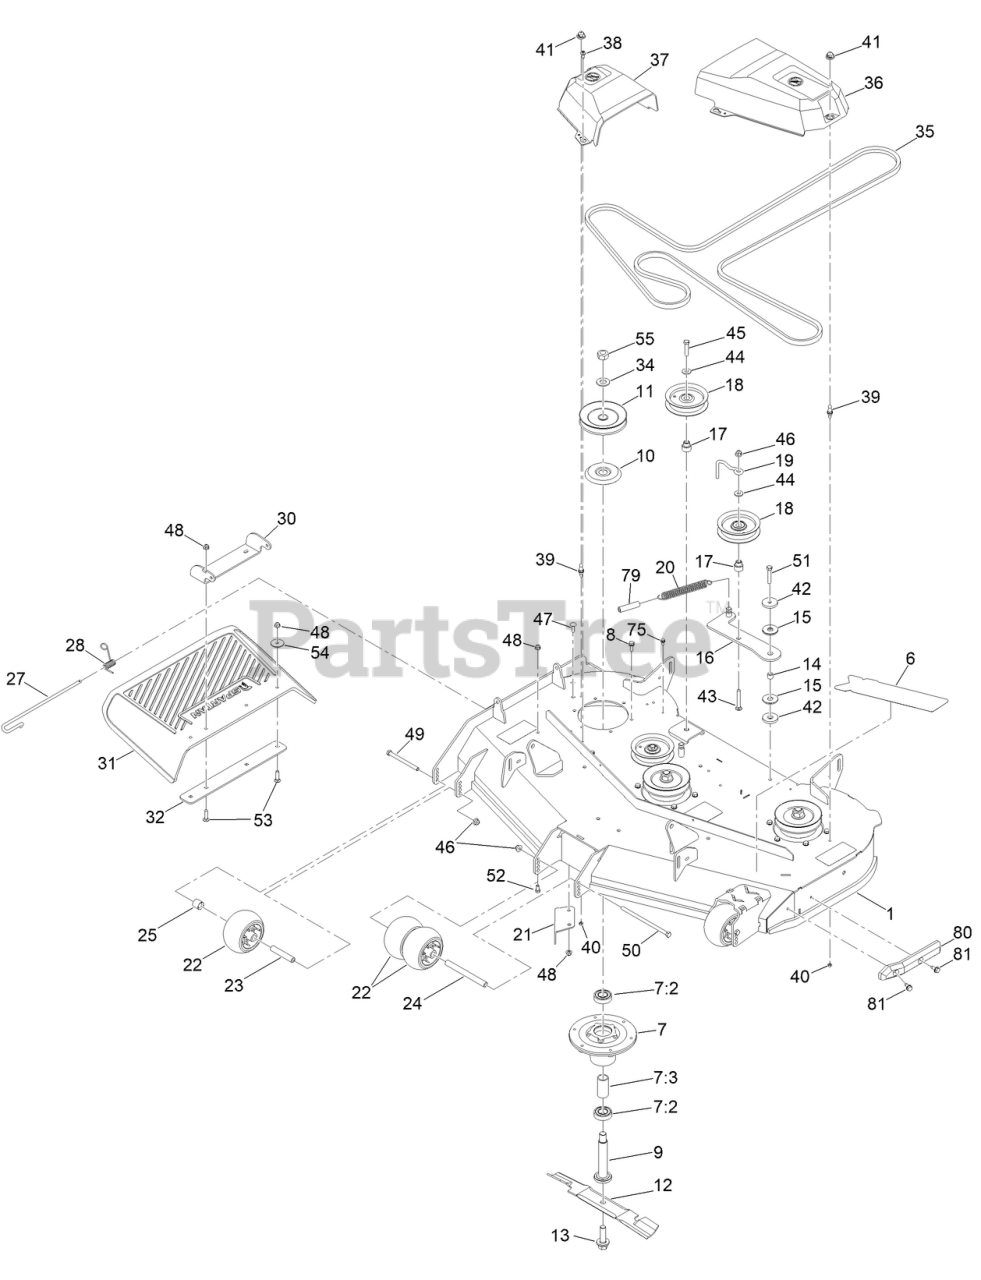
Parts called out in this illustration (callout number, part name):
1	48 IN DECK DECAL ASM
6	DECAL-XTF
7	SPINDLE ASM
7:2	BEARING-BALL
7:3	SPACER-BEARING
8	SCREW-TAPTITE
9	SHAFT-SPINDLE
10	SHIELD-BEARING
11	PULLEY
12	BLADE-HI FLO, 16.50 INCH
13	SCREW-BLADE
14	SPACER
15	WASHER-FRICTION, COMPOSITE
16	IDLER ARM ASM
17	BUSHING-IDLER
18	PULLEY-IDLER, FLAT
19	GUIDE-BELT, IDLER
20	SPRING-EXTENSION
21	BAFFLE-CUTOFF
22	ROLLER-SCALP, ANTI
23	TUBE-SPANNER
24	SPACER-WHEEL
25	SPACER-AXLE, REAR
27	PIN-CHUTE
28	SPRING-TORSION
30	BRACKET-DEFLECTOR, UPPER
31	DEFLECTOR-DISCHARGE
32	PLATE-DEFLECTOR
34	WASHER
35	V-BELT
36	COVER-BELT, LH
37	COVER-BELT, RH
38	SCREW-SHOULDER
39	STUD-BALL
40	NUT-LOCK
41	GROMMET-BALL
42	WASHER-PLAIN
43	SCREW-CARR
44	WASHER-HARDENED
45	SCREW-HH
46	NUT-HF, NI
47	SCREW-CARR
48	NUT-HF, NI
49	SCREW-HH
50	SCREW-HH
51	SCREW-HH
52	SCREW-HH
53	SCREW-CARR
54	WASHER-FLAT
55	NUT-HEX
75	SCREW-HWH
79	HOSE-BREATHER
80	BUMPER-DECK
81	SCREW-HWHTF
